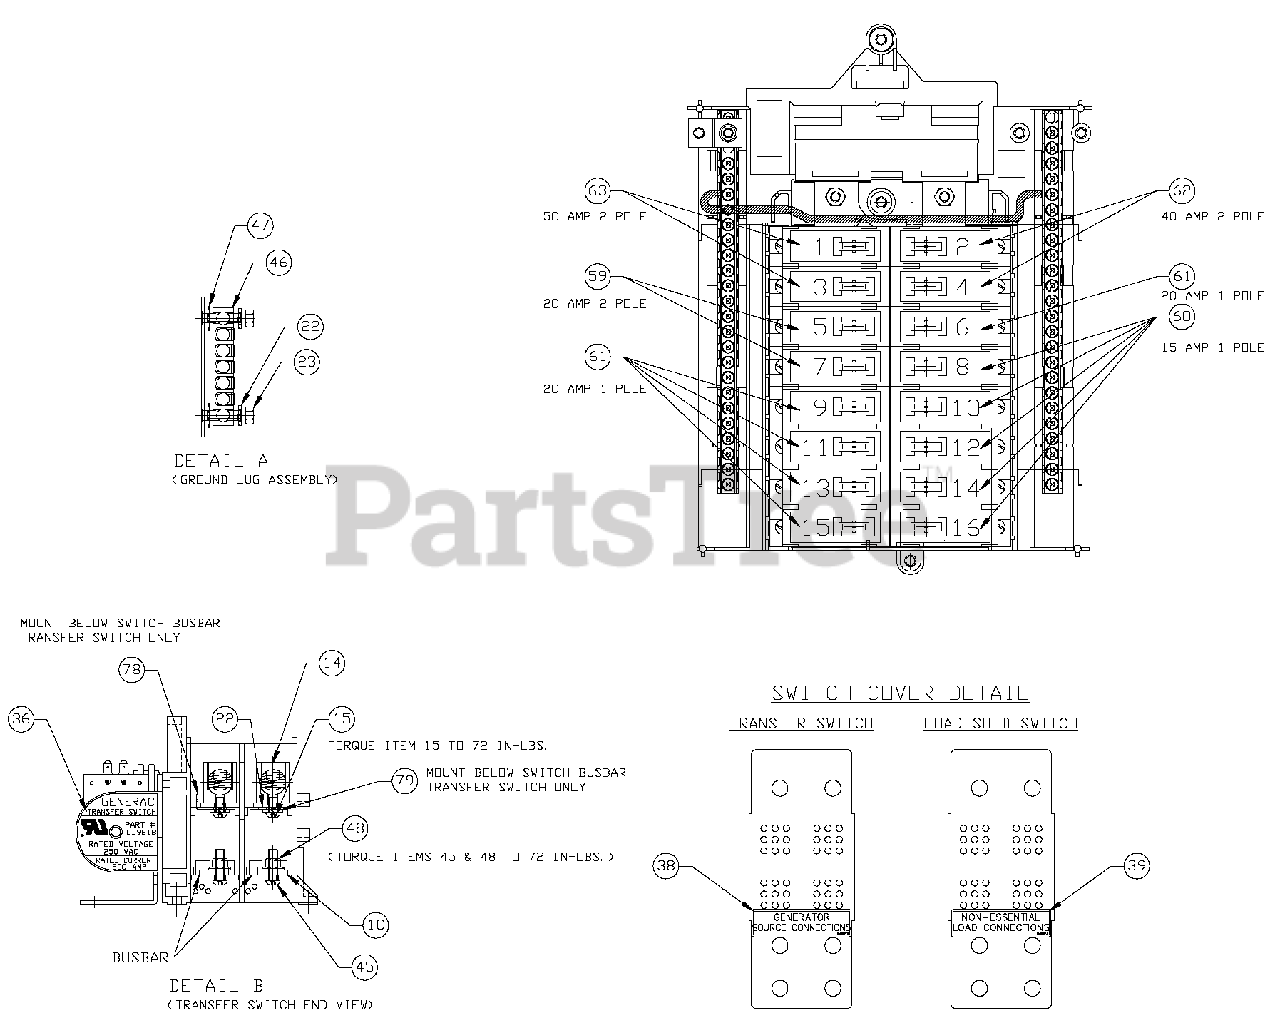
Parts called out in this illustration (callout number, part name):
15	SCREW BHSC 1/4-20 X 3/8
22	WASHER LOCK M6-1/4
23	NUT HEX 1/4-20 SS
36	DECAL, TRANSFER SWITCH INFO
38	DECAL, GENERATOR SOURCE CONNECTION
39	DECAL, NON-ESSENTIAL LOAD CONN
45	SCREW BHSC 1/4-20 X 3/4
46	GROUND BAR (5) 2-14 AWG CONN
47	WASHER SHAKEPROOF EXT 1/4 STL
48	NUT HEX FL WHIZ 1/4-20
59	CB 0020A 2P PLUG IN
60	CB 0015A 1P PLUG IN
61	CB 0020A 1P PLUG IN
62	CB 0040A 2P PLUG IN
63	CB 0050A 2P PLUG IN
78	90 DEGREE DN SPADE CONNECTOR
79	STRAIGHT SPADE CONNECTOR
